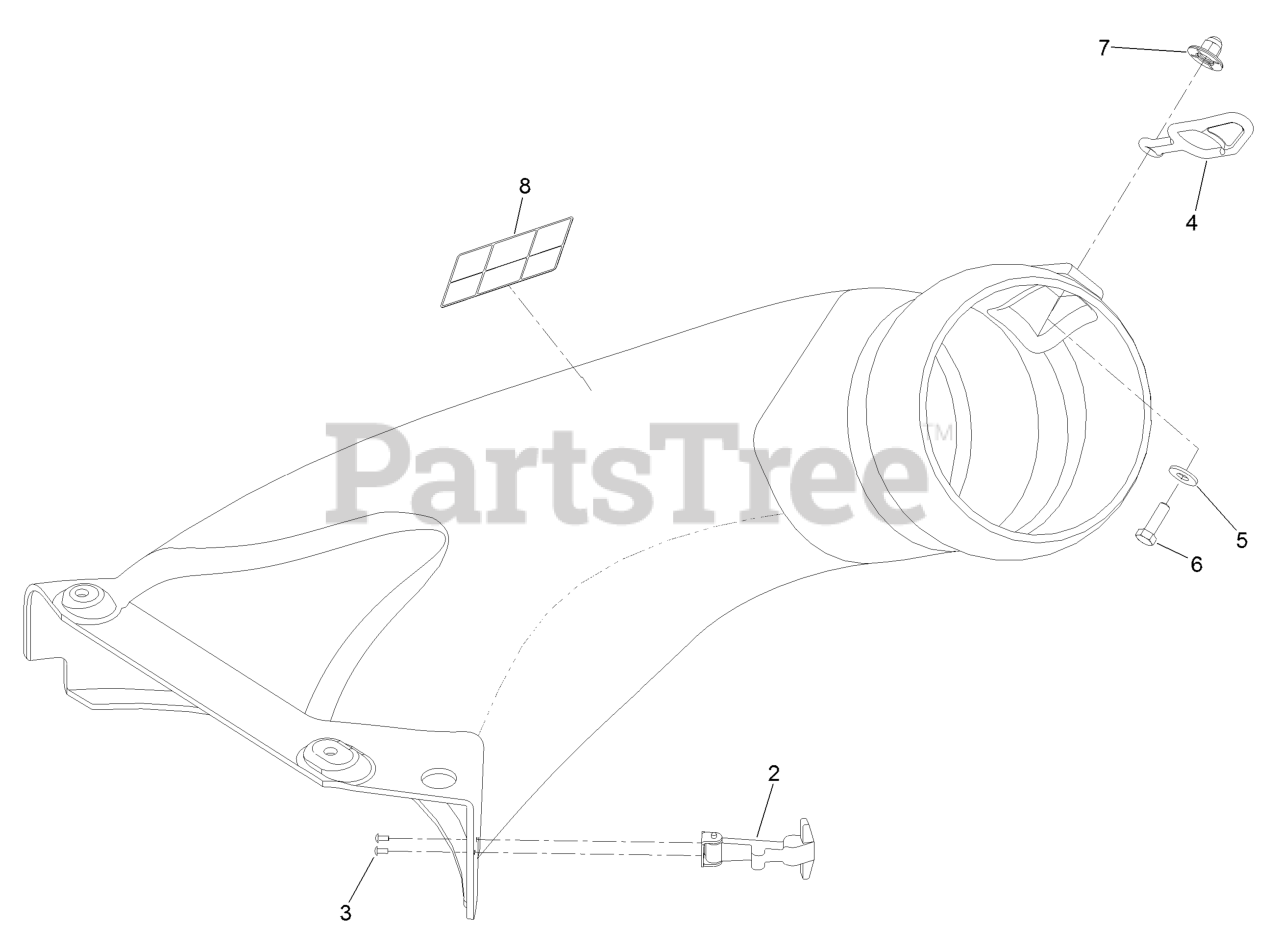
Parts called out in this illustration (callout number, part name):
2	HANDLE ASM
3	RIVET-POP
4	RETAINER-DUCT
5	WASHER-FLAT
6	SCREW-HH
7	NUT-IMPELLER
8	DECAL-DANGER
